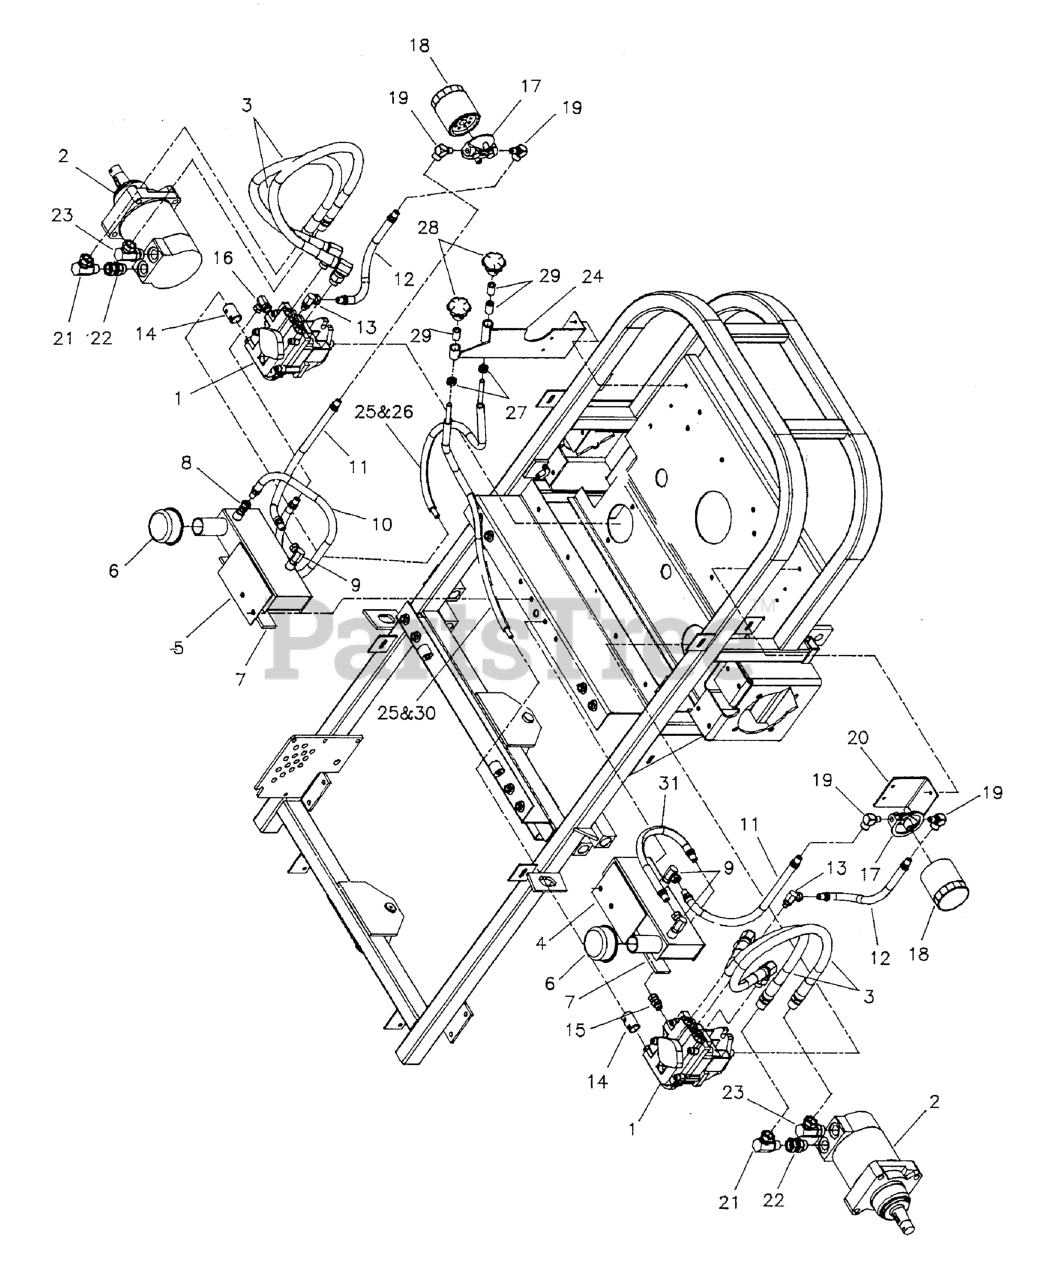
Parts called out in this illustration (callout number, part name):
1	HYDRAULIC PUMP
2	HYDRAULIC WHEEL MOTOR
3	REPLACE WITH 5413138 + 5022633, HYDRAULIC HOSE ASSEMBLY + FITTING
4	RESERVOIR, Oil, Left
5	RESERVOIR, Oil, Right
6	BREATHER
7	RUBBER PAD
8	FITTING, 1/4" NPT Straight Swivel
9	FITTING, 1/4" NPT 90 Degree Swivel
10	HYDRO HOSE ASSEMBLY, 24"
11	HYDRO HOSE ASSEMBLY, 12"
12	HYDRO HOSE ASSEMBLY, 11"
13	FITTING, 7/16" O-Ring 90 Degree Swivel
14	COLLAR, Dump Valve
15	FITTING, 9/16" O-Ring Straight Swivel
16	FITTING, 9/16 O-RING - 1/4 NPT, 90 DEG
17	FILTER HEAD
18	FILTER
19	FITTING, 1/4 NPT, 90 Deg.
20	MOUNT, Filter head
21	FITTING, 1/2 NPT Swivel, 90 Deg.
22	FITTING, 7/8" O-Ring Straight Swivel
23	FITTING, O-Ring, 90 Deg. Swivel
24	MOUNT, Filter, Right
25	SHAFT, 3/8" Flexible
26	HOUSING, Flex Shaft
27	COLLAR, 3/8" Set
28	KNOB, Dump Valve
29	BUSHING, Brass
30	HOUSING, Flex Shaft
31	HYDRO HOSE ASSEMBLY, 14"
